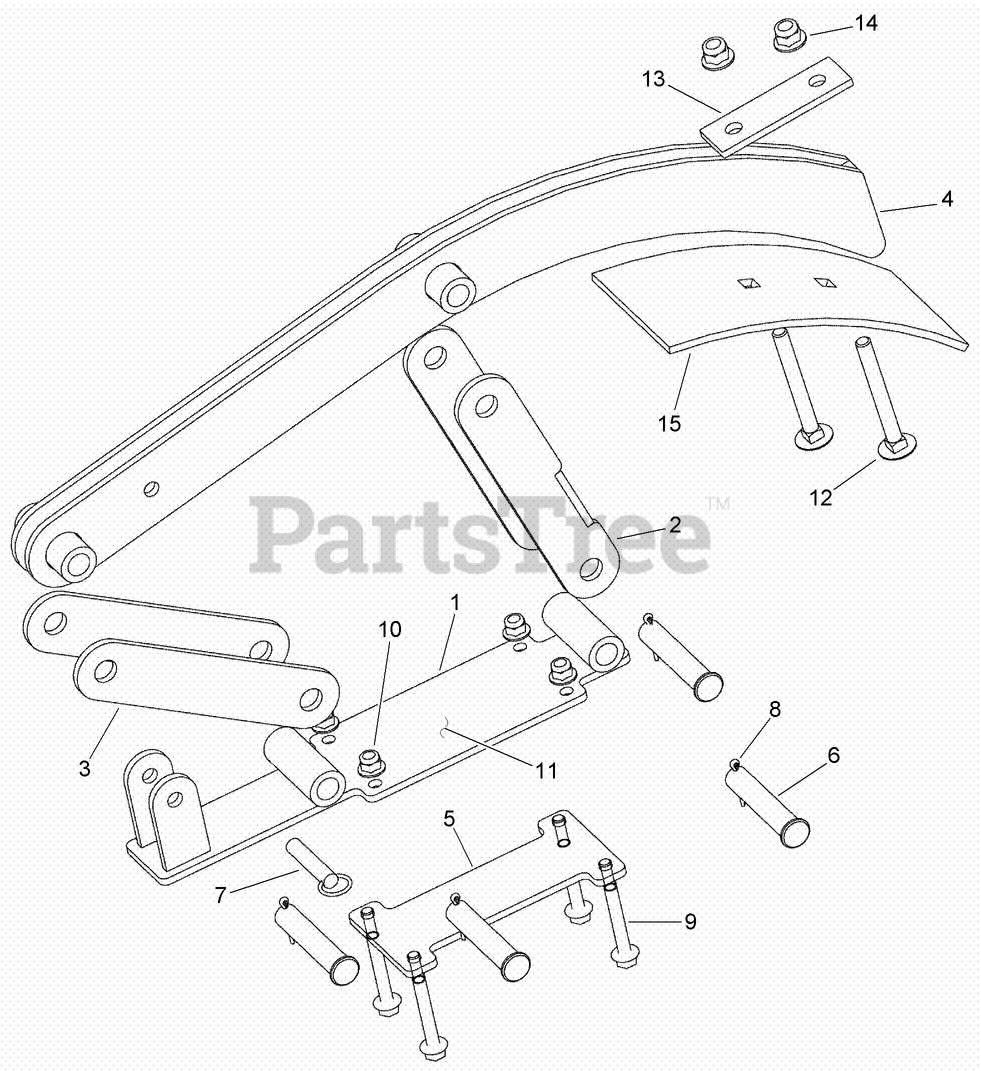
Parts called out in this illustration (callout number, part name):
1	PLATE-CRUMBER
2	LINKAGE-FRONT
3	LINK-REAR
4	PLATE-BLADE
5	PLATE-CLAMP
6	PIN-LINKAGE
7	PIN-RETAINING
8	PIN - Cotter, .156 x 1.25 in Zn
9	SCREW-FLANGE, METRIC
10	NUT-FLANGE, NYLOCK
11	DECAL-DANGER, ENTANGLE HAZZARD
12	BOLT-CARRIAGE, METRIC
13	SPACER
14	NUT-HHF, LOCK
15	PLATE-CRUMBERSHOE, 4 INCH
15	PLATE-CRUMBERSHOE, 6 INCH
15	CRUMBER SHOE - 8in
